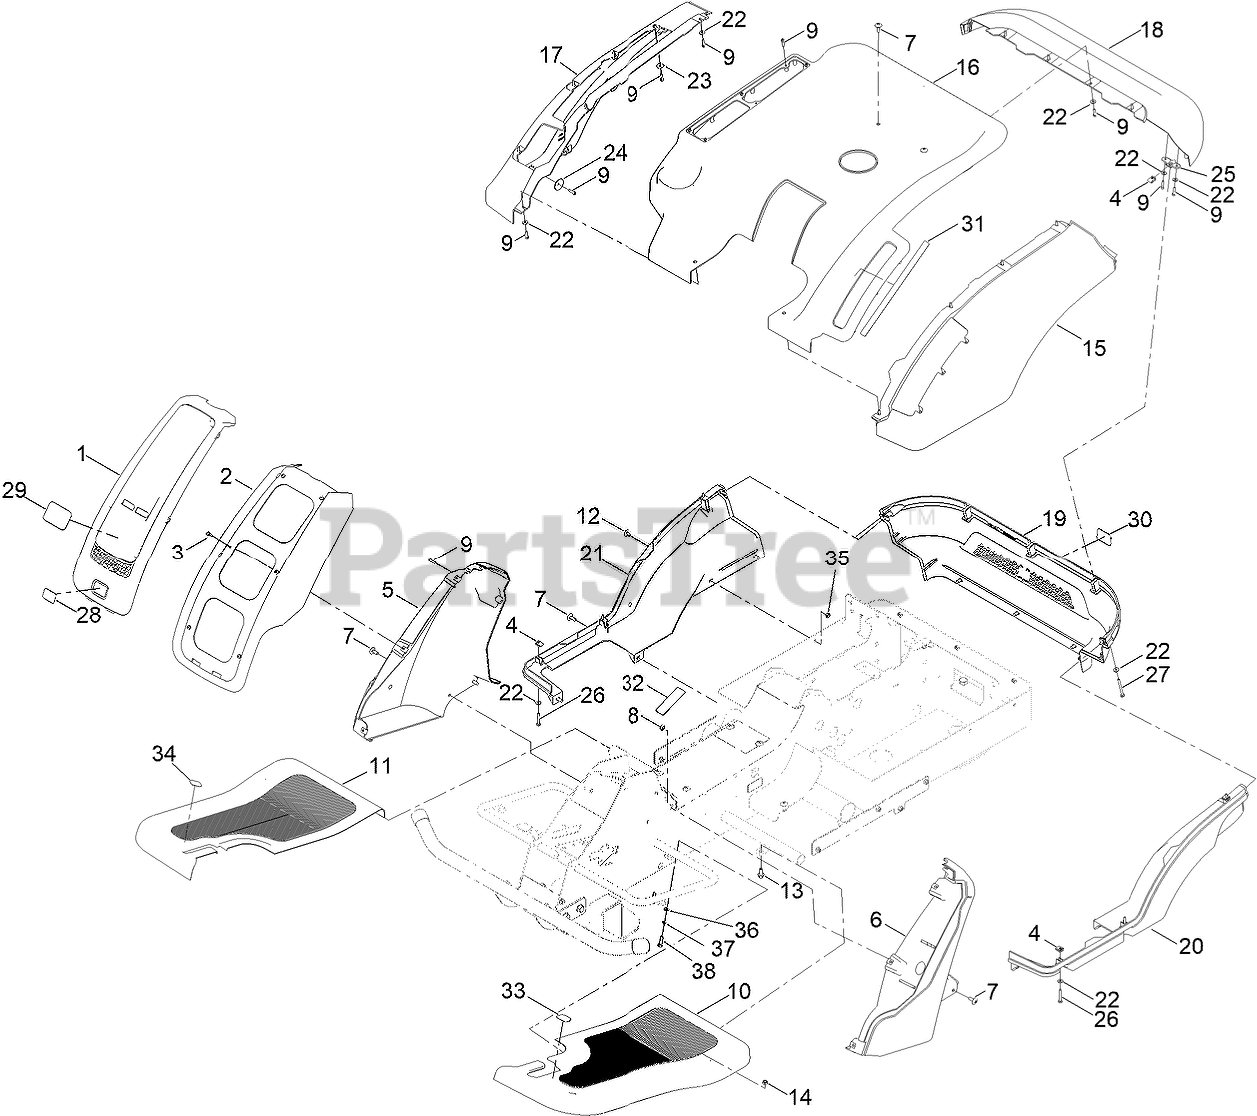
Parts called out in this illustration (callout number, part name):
1	FRONT PANEL, STEERING COLUMN
2	FRONT PANEL MOUTNING, STEERING COLUMN
3	BOLT PH
4	CLIP, BOLT
5	RH PANEL, STEERING COLUMN
6	LH PANEL, STEERING COLUMN
7	CAP BOLT
8	NUT-NYLOC
9	BOLT PH
10	PANEL FLOOR, LH
11	PANEL FLOOR, RH
12	CAP BOLT
13	SCREW-HHF
15	COVER, LH/MIDDLE
16	COVER, TOP
17	COVER, RH/MIDDLE
18	COVER, TOP/REAR
19	COVER, MIDDLE/REAR
20	COVER, RH/BOTTOM
21	COVER, LH/BOTTOM
22	WASHER
23	WASHER
24	WASHER, BENT
25	MOUNTNG BRACKET, REAR PANEL
26	BOLT PH
27	BOLT PH
28	DECAL - ERIDER BATTERY
29	DECAL - TORO LOGO
30	DECAL - TORO LOGO
31	DECAL - HOC
32	DECAL - PARKING BRAKE
33	DECAL - BRAKE
34	DECAL - PROPEL
36	WASHER
37	SPRING WASHER
